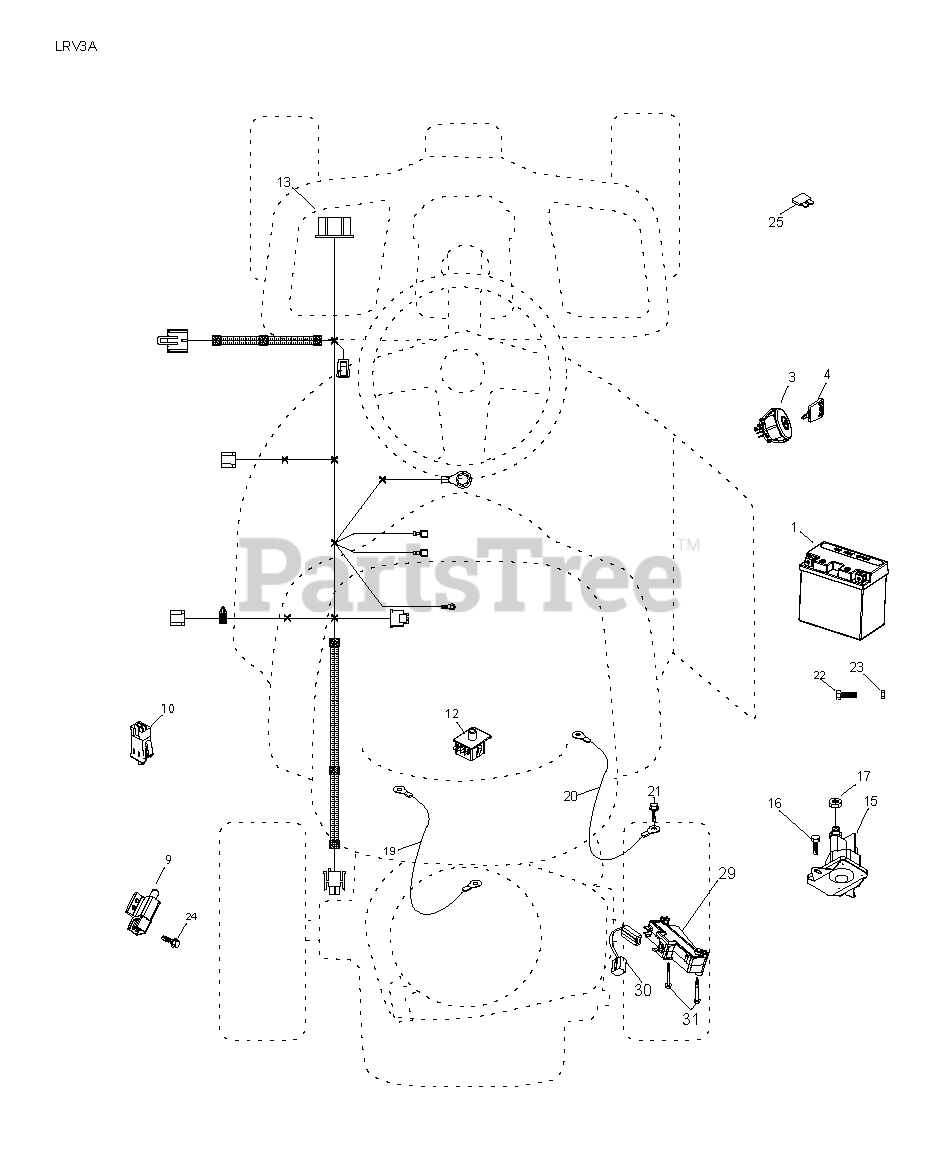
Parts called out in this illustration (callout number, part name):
1	BATTERY.6A.12V.LEOCH
3	SWITCH.IGN.DELTA.W.LGH.ROS
4	KEY.CHAIN.BLISTER.PACK.GEN.USA
9	SWITCH INTERLOCKT
10	SWITCH INTERLOOK PUSH-IN
12	SWITCH.SEAT.DP W/RAMPS
13	ELECTRICAL.LRVB.GEARDRIVE
15	SOLENOID.W/BRASS.PLUNGER
16	SCREW
17	NUT
19	CABLE.STARTER.6GA.11"RED
20	CABLE GROUND 6 GA. 12" BLACK
21	SCREW 5/16"
22	SCREW.HEX.M5X0.8.9MM (2 2)
23	NUT.M5.(.393X.275)
24	SCR #10-24 X .75 SKT HD BLK
29	MODULE.REVERSE.ROS
30	JUMPER.PIGTAIL.ROS.LRVB
31	SCREW.PLASTITE
